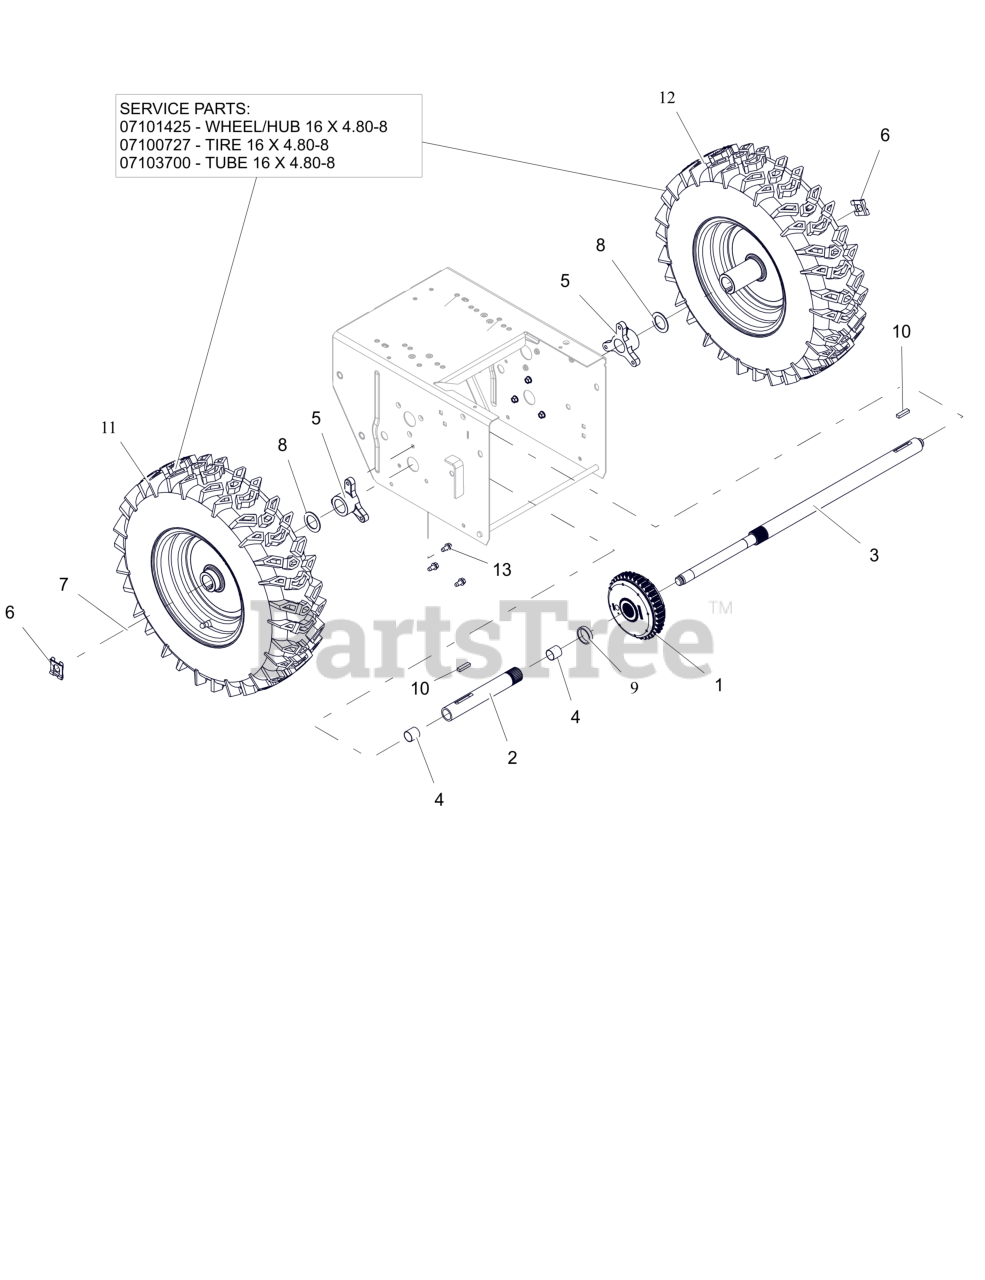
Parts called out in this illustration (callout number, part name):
1	DIFFERENTIAL, AUTOMATIC
2	AXLE, SHORT - W/BUSHINGS
3	AXLE,LONG-DELUXE AUTO DIFF
4	BSHG-SLV .706X.764X.75 BRZ
5	BUSHING, AXLE
6	CLIP, SNAP .625 DIA
7	RG-RTNG-EXT .625X.042
8	WSHR, FLT 1.010X1.505X.062 ZCC
9	BSHG, SLV 1.062X1.228X.268
10	KEY-RECT .25X.188X1.00
11	TIRE/WHEEL RH 16X4.8-8 DIFF T2
11	HUB, WHEEL-16X4.8-8
11	TIRE, 4.80-8 K478
11	TUBE
12	TIRE/WHEEL LH 16X4.8-8 DIFF T2
12	HUB, WHEEL-16X4.8-8
12	TIRE, 4.80-8 K478
12	TUBE
13	SCR-TAP .25-20X.50 HWH ZCC
